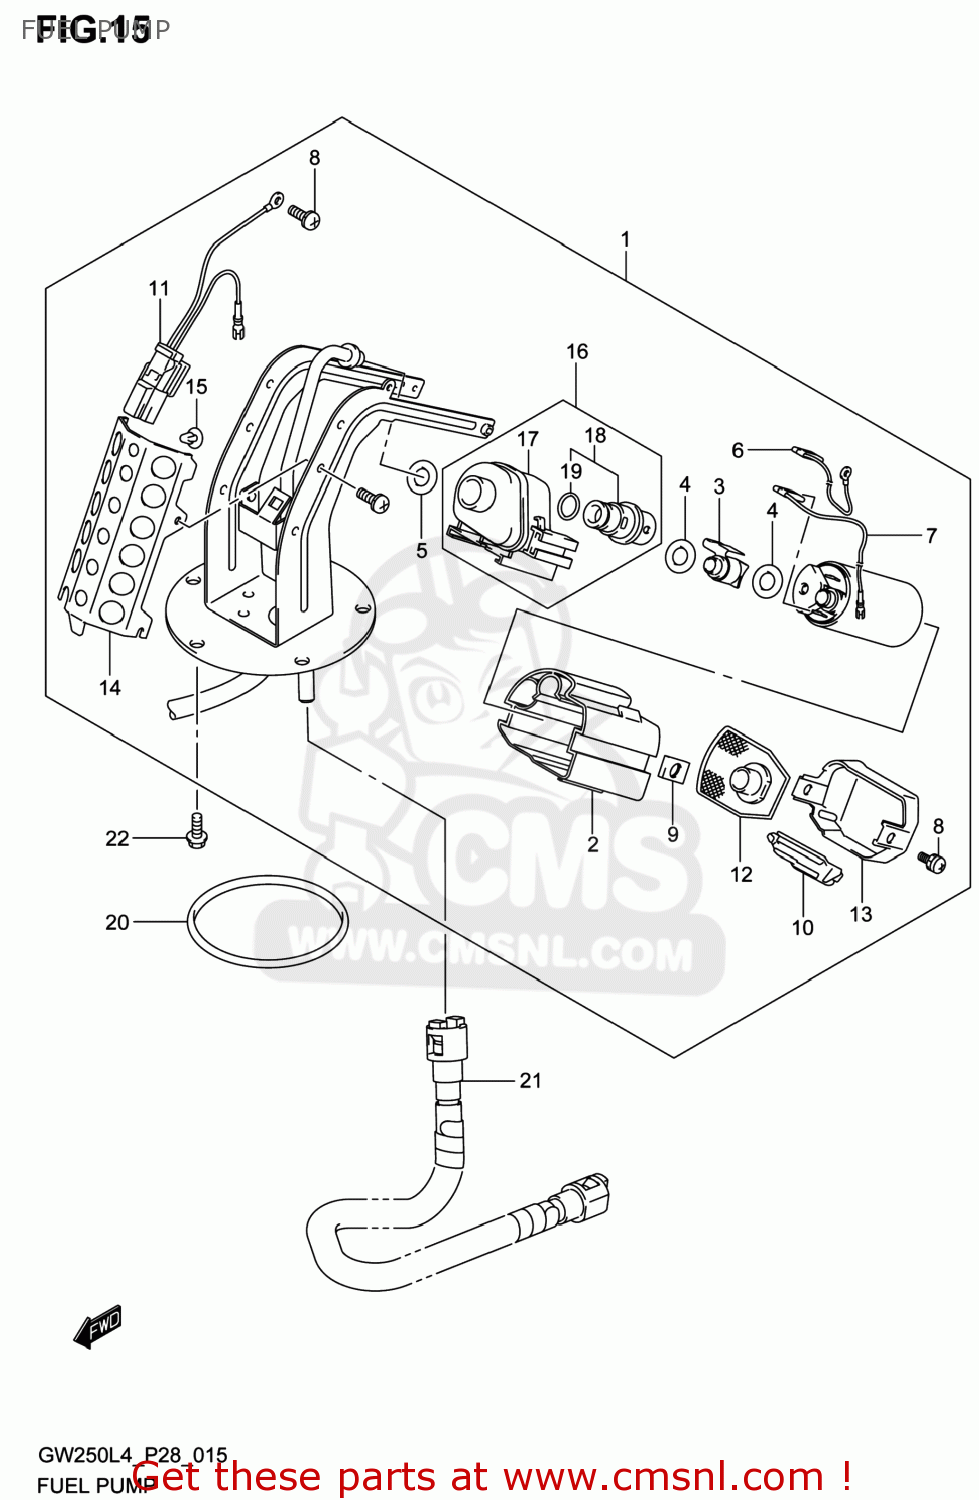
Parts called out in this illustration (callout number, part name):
1	PUMP ASSY,FUEL
2	CUP
3	JOINT
4	O RING
5	O RING
6	WIRE,EARTH
7	WIRE,LEAD
8	SCREW
9	STOPPER
10	COVER,CUP
11	HARNESS,GAUGE
12	STRAINER
13	COVER,DUST
14	GUARD
15	STOPPER
16	REGULATOR ASSY,FUEL
17	FILTER
18	REGULATOR ASSY,FUEL
19	O RING
20	O RING,FUEL PUMP
21	HOSE,FUEL
22	BOLT
